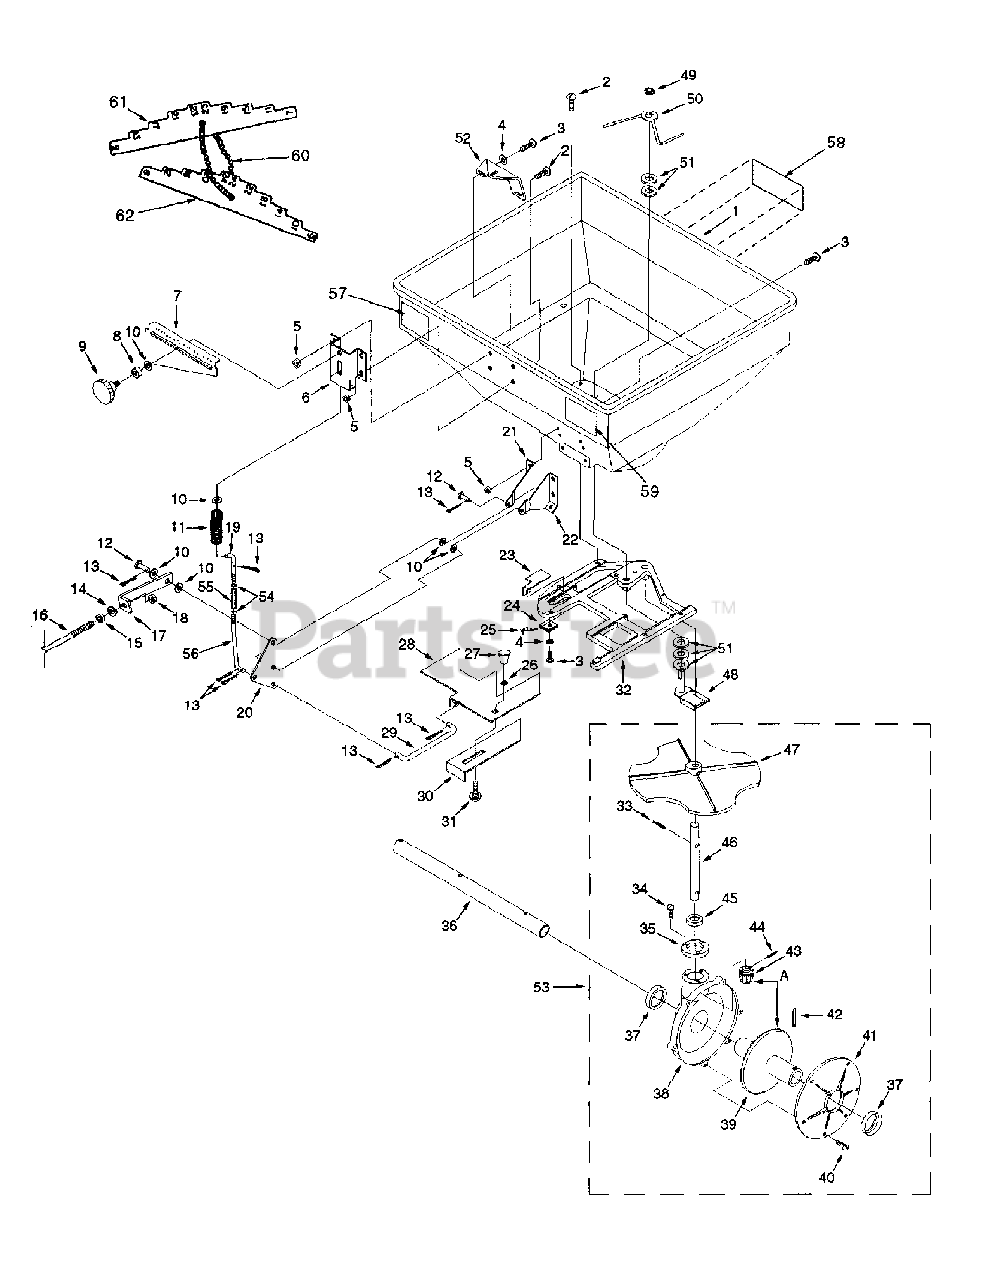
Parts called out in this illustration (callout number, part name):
1	Hopper
2	Machine Screw, #10-24 x 1/2, SS
3	Machine Screw, #10-24 x 5/8, SS
4	Flat Washer, #10, SS
5	Hex Nut, #10-24 Nylock, SS
6	Bracket, Spring and Rod Guide, SS
7	Bracket, Calibrating Slide, SS
8	Spacer, Nylon .500 x .257 x .500
9	Knob, Calibrating Slide
10	Flat Washer, 1/4 SS
11	Calibrating Spring, SS
12	Clevis Pin, 1/4 x 1/2, SS
13	Cotter Pin, 3/32 x 1/2, SS
14	Lock Washer, 5/16, SS
15	Hex Nut, 5/16-18, SS
16	Lever Rod, SS
17	Bracket, Lever Rod Adjusting, SS
18	Hex Nut, 5/16-18 Nylock, SS
19	Calibrating Rod, SS
20	Bellcrank Pivot, SS
21	Bellcrank Pivot Mount, LH, SS
22	Bellcrank Pivot Mount, RH, SS
23	Remote Slide Plate, SS
24	Conduit Clip
25	Cable, Remote Control
26	Flat Washer, 1/4, Nylon
27	Knob, Third Hole Slide Plate
28	Main Slide Plate, SS
29	Linkage Rod, Slide Plate, SS
30	Slide Plate, Third Hole, SS
31	Carriage Bolt, #10-24 x 3/8, SS
32	Guide, Shut Off Plate
33	Roll Pin, 1/8 x 7/8, SS
34	Screw, #10 x 5/8 T-A Hex Slot Hd., SS
35	Cap, Gear Set
36	Spreader Axle, SS
37	Seal, Housing and Cover
38	Housing, Gear Set
39	Gear
40	Screw, #6 x 5/8 T-A Pan Hd. Phil., SS
41	Cover, Gear Set
42	Roll Pin, 5/32 x 1-1/4, SS
43	Pinion Gear
44	Roll Pin, 1/8 x 5/8, SS
45	Seal, Gear Set Cap
46	Impeller Shaft, SS
47	Impeller
48	Agitator Cam, SS
49	Spring Clip
50	Agitator Arm
51	Plastic Washer
52	Calibrating Window
53	Kit, Impeller and Gear Set
54	Nut, 1/4"-28 SS
55	Calibrating Rod Adjuster
56	Lower Calibrating Rod, SS
57	"USA" Decal
58	MTD HWSS 100 Decal
59	100 lb. Capacity Decal
60	Chain
61	Calibration Gauge-Odd
62	Calibration Gauge-Even
